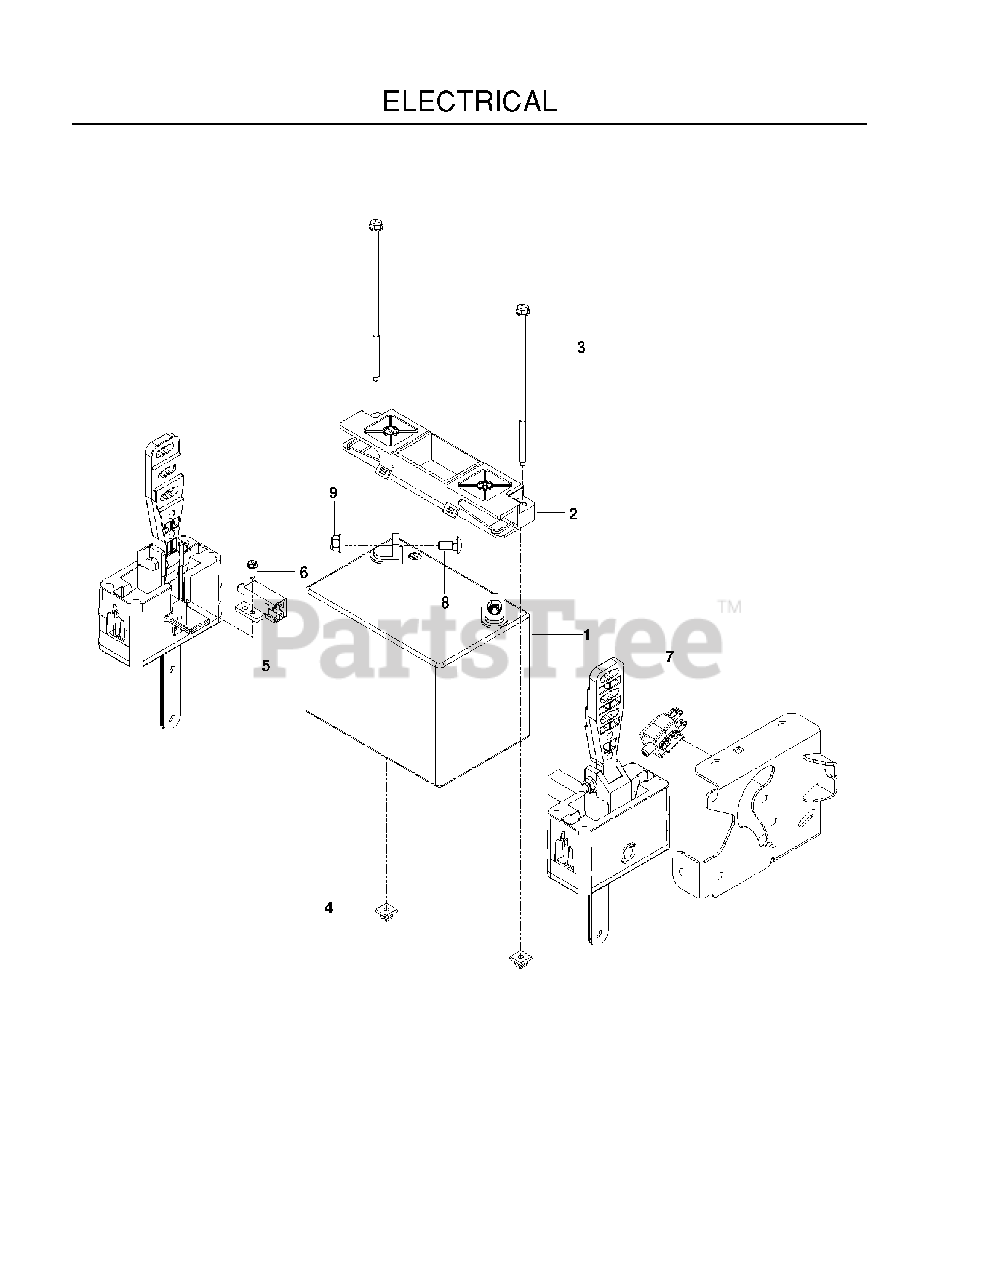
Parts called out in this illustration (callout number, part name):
1	BATTERY, 12 V 330 AMP
2	BATTERY HOLD DOWN
3	Bolt, 1/4-20 X 7.5
4	PUSH NUT-NYLON
5	SWITCH, INTERLOCK
6	SCREW #10 X 1/2 SELF TAPPING
7	SWITCH, BRAKE 3P
8	BOLT 5/16C X 3/4" CARRIAGE
9	5/16-18 NYLOC FLANGE NUT
